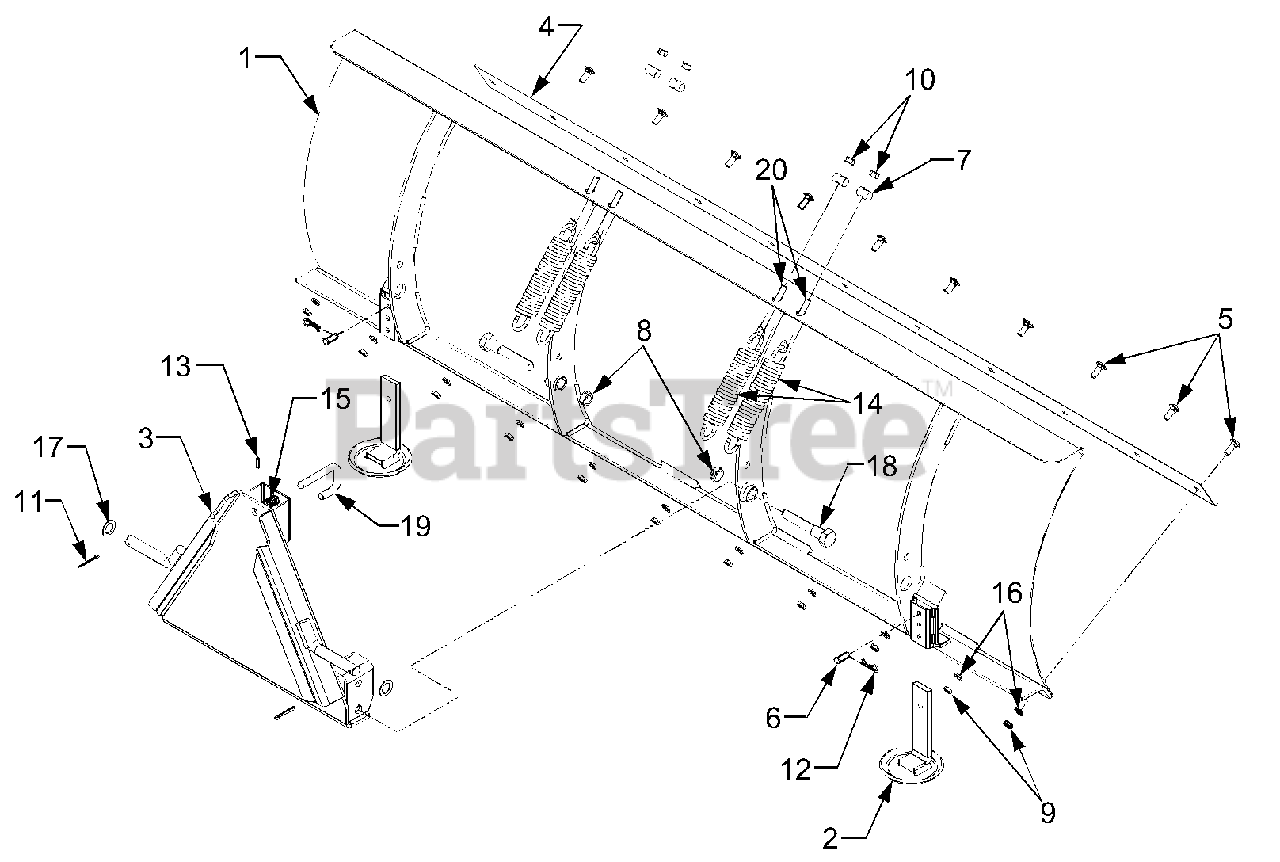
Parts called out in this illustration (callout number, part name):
1	Blade Assembly 72 inch
3	Frame, Blade Mounting
4	Blade, Scraper
5	Screw, Carriage, 3/8-16 x 1.0
6	Pin, Clevis,.375 x.969
7	Spring Roller
8	Nut, Jam Lock, 5/8-11
9	Nut, Jam, 3/8-16 GR5
10	Nut, Hex, 3/8-16 GR8
11	Pin, Cotter, 3/16 x 1.5
12	Pin, Internal Cotter, .092 x 1.64
13	Pin, Spirol 3/16 x 3/4
14	Spring, Extension, 1.5 x 8.0
15	Spring, Compression, .57 x 2.09
16	Washer, Lock, 3/8
17	Washer, Flat, .793 x 1.24 x .06 Hdn
18	Screw, Shoulder
19	Pin, Front Hitch
20	Rod, Spring Adjustment
